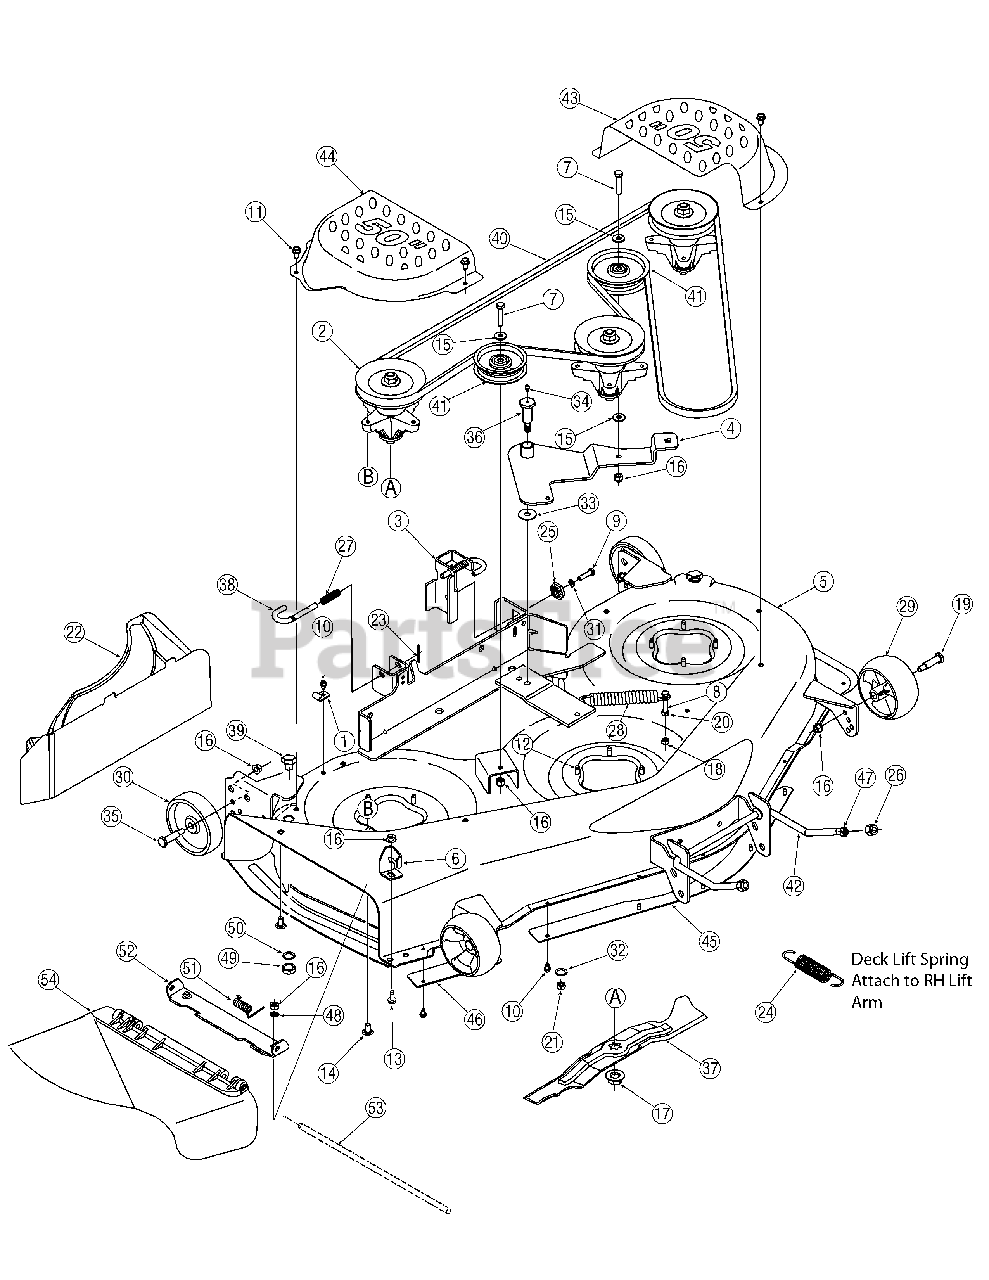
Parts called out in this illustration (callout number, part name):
1	Hook, Retainer
2	Spindle Assembly
7	Screw, 3/8-16, 1.75
8	Screw, 5/16-18 x 2.00
9	Screw, 5/16-18, 1.25, Gr5
10	Screw, 1/4-20 x 0.5
11	Screw, 5/16-18 x.500
12	Screw, 5/16-18 x.75
13	Screw, 3/8-16 x 1.0
14	Screw, Carriage, 3/8-16 x.75
15	Washer, Flat,.406 x.875 x.059
16	Nut, Nylon Lock, 3/8-16
17	Nut, Hex, Flange, 5/8-18
18	Nut, Nylon Lock, 5/16-18
19	Shld. Screw, 1/2 x 2.50 Lg.
20	Nut, Hex, 5/16-18, Gr5
21	Nut, 7/16-14
22	Mulch Plug (if equipped)
23	Pin, Cotter, 1/8 x 1.25
24	Exten. Spring, 1.15 Dia. x 5.99 Lg
25	Deck Adjustment Gear
26	Lock Nut, Hex, 1/2-13, Nylon
27	Spring, Compression,.531 x .175
28	Spring, Extension,.94 x 6.74
29	Deck Wheel, 5.0
30	Deck Wheel, 5.0
31	Washer, Lock, 5/16, Regular
32	Washer, Bell,.45 x 1.0 x. x.062
33	Washer, Flat,.442 x 1.38 x. .060
34	Fitting, Lube, 3/16
35	Shoulder Screw
36	Screw, Shoulder,.68 x 1.59
37	Blade
38	Rod, Deck Release.375 Dia
39	Screw Plug, M16 x 1.5
40	Belt, V-Type, Aramid
41	Pulley, Idler, 3.5"
42	Rod, Deck Adjustment
47	Hex Nut, 1/2-13
48	Push Nut, 3/8
49	Hex Nut, M16-1.5
50	Lock Washer, 5/8
51	Torsion Spring,.44ID x 2.10
53	Hinge Pin
54	Chute Deflector
